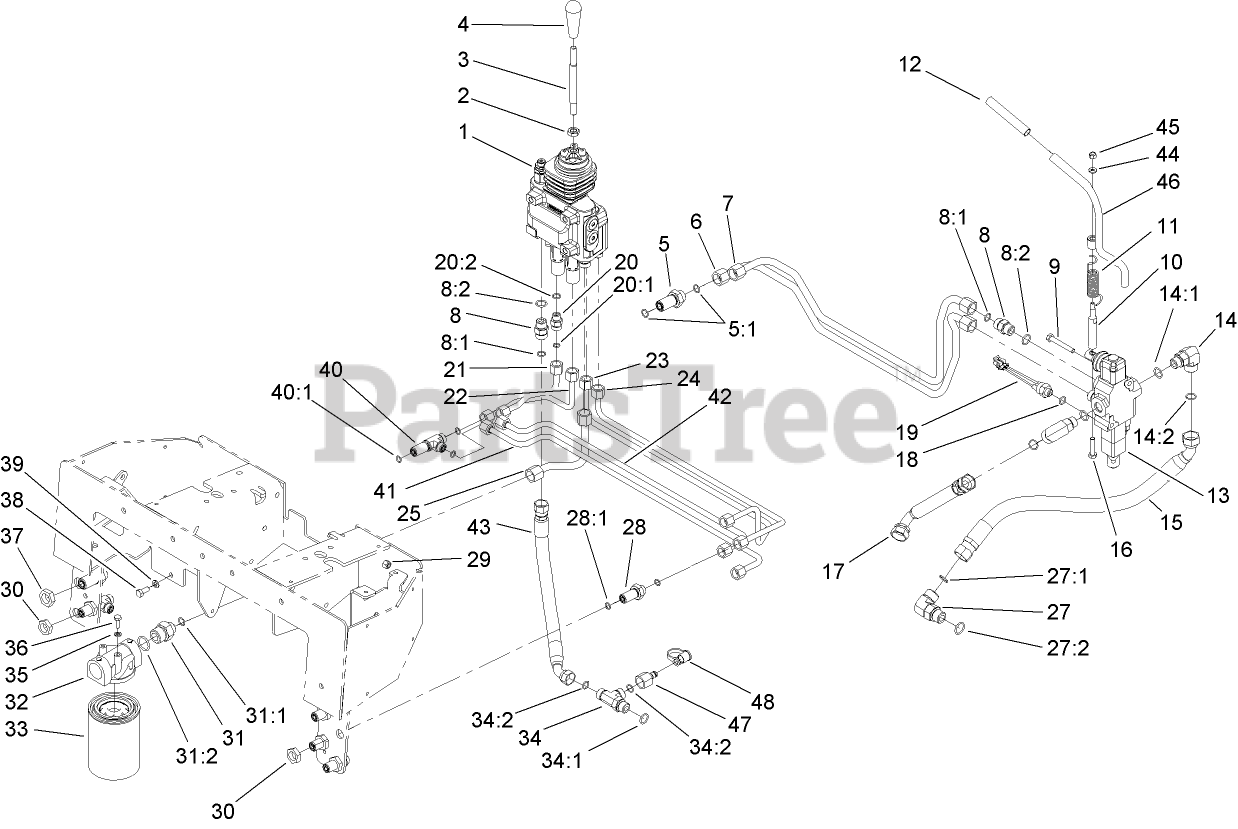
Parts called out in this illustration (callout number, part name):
1	2 SPOOL VALVE ASM
3	SHAFT-HANDLE, LOADER
5	FITTING-BULKHEAD
5:1	O-RING
6	TUBE-HYD
7	TUBE-HYD
8	FITTING-STRAIGHT
8:1	O-RING
8:2	O-RING
9	SCREW-HH
10	SPACER-HIFLO
11	SPRING-TORSION
12	GRIP-RUBBER
13	1 SPOOL VALVE ASM
14	Fitting-Elbow, 90 DEG
14:1	O-RING
14:2	O-RING
15	HYD HOSE ASM
16	SCREW
17	HYD HOSE ASM
18	O-RING
19	SWITCH-BALL
20	FITTING-STRAIGHT
20:1	O-RING
20:2	O-RING
21	TUBE-HYD
22	TUBE-HYD
23	TUBE-HYD
24	TUBE-HYD
25	TUBE-HYD
27	FITTING-ELBOW-90
27:1	O-RING
27:2	O-RING
28	FITTING-STRAIGHT, BULKHEAD
28:1	O-RING
29	NUT-LOCK, NI
30	NUT-LOCK
31	FITTING-STR
31:1	O-RING
31:2	O-RING
32	HEAD-FILTER
33	FILTER-OIL
34	FITTING-TEE
34:1	O-RING
34:2	O-RING
35	WASHER-LOCK
36	SCREW-HH
37	NUT-BULKHEAD
38	SCREW-HH
39	WASHER-LOCK
40	FITTING-TEE, BULKHEAD
40:1	O-RING
41	TUBE-HYD
42	TUBE-HYD
43	HYD HOSE ASM
44	WASHER-FLAT
45	NUT-LOCK, NI
46	LEVER-AUXILIARY
47	FITTING
48	CAP-DUST
